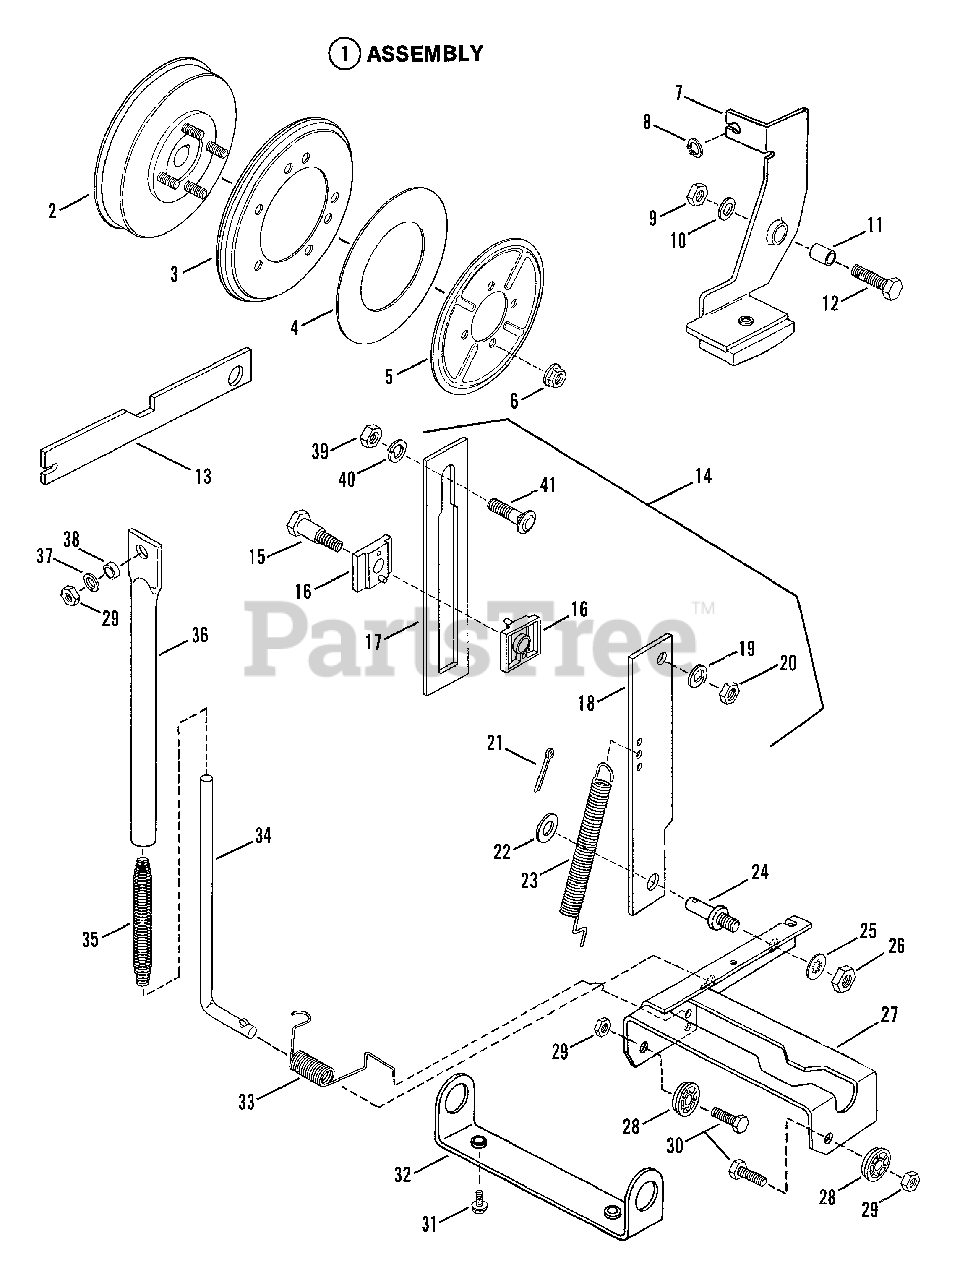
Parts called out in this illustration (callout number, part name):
1	ASSEMBLY, Smooth Clutch
2	HUB, Driven Disc
3	DISC, Driven
4	WASHER, Thrust
5	PLATE
6	NUT, 5/16-18 Hex Flange Lock
7	ASSEMBLY, Brake Lever
8	RING, Retaining
9	NUT, 1/4-28 Hex Lock
10	WASHER, 1/4 Flat
11	SPACER
12	SCREW, 1/4-28x1" Hex Head Cap
13	TOOL, Smooth Clutch
14	ASSEMBLY, Guide & Link
15	BOLT, 5/16-18 Shoulder
16	SLIDE-HALF
17	GUIDE, Clutch Link
18	LINK, Clutch
19	WASHER, 5/16 Split Lock
20	NUT, 5/16-18 Hex
21	COTTER-PIN, 3/32x1"
22	WASHER, 3/8" Flat
23	SPRING, Clutch Brake
24	STUD, Clutch Link
25	WASHER, 3/8 Internal Tooth Lock
26	NUT, 3/8 Hex
27	LIFT, Yoke
28	BEARING, Yoke
29	NUT, 5/16-24 Hex Center Lock
30	SCREW, 5/16-24x3/4" Hex Head Cap
31	SCREW, 3/8-16x1/2" Self-Tapping
32	COLLAR, Yoke
33	SPRING
34	ROD
35	SPRING (34 Coils)
37	WASHER, 5/16 Flat
38	ROLLER
39	NUT, 3/8-16 Hex
40	WASHER, 3/8 Split Lock
41	BOLT, 3/8-16x3/4" Short Neck Carriage
